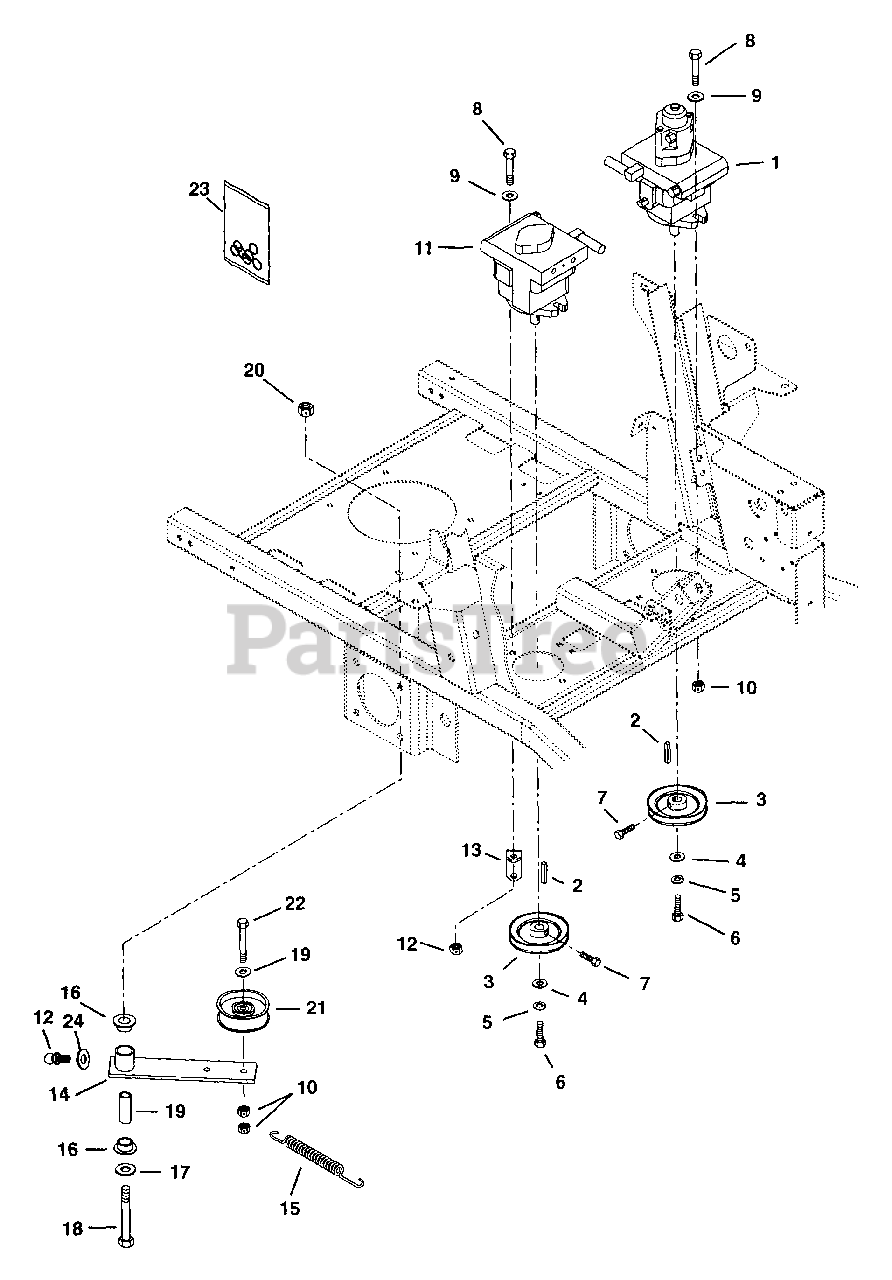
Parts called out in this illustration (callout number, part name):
1	Hydrostat BDP with Auxiliary
2	Key-Straight 5mm x 25mm x 5mm
3	Sheave 4.0 x .199
4	Washer-Flat-Steel .25 x 1.0 x .048
5	Washer-Locking .25 x .062
6	Bolt-Hex M6 x 1.0 x 12
7	Bolt-Hex .25-20 x .50 Grade 5
8	Bolt-Hex .38-16 x 1.25 Grade 5
9	Washer-Flat-Steel .390 x .75 x .125
10	Nut-Locking-Center .38-16
11	Variable-Displace Pump
12	Fitting-Lube .25-28 x .256
13	Anchor-Spring-Idler
14	Arm-Ground Drive Idler
15	Spring-Tension .120 x .845 x 6.500
16	Bushing-Flange .762 x 1.0 x .580 x 1.48
17	Washer-Flat-Steel .531 x 1.06 x .095
18	Bolt-Hex .50-13 x 3.00 Grade 5
19	Bushing-Steel .560 x .745 x 2.04
20	Nut-Locking-Center .50-13
21	Assembly-Idler Pulley
22	Bolt-Hex .38-16 x 2.25 Grade 5
23	Kit-Pump Seal
24	Washer-Flat-Steel .265 x .50 x .087
